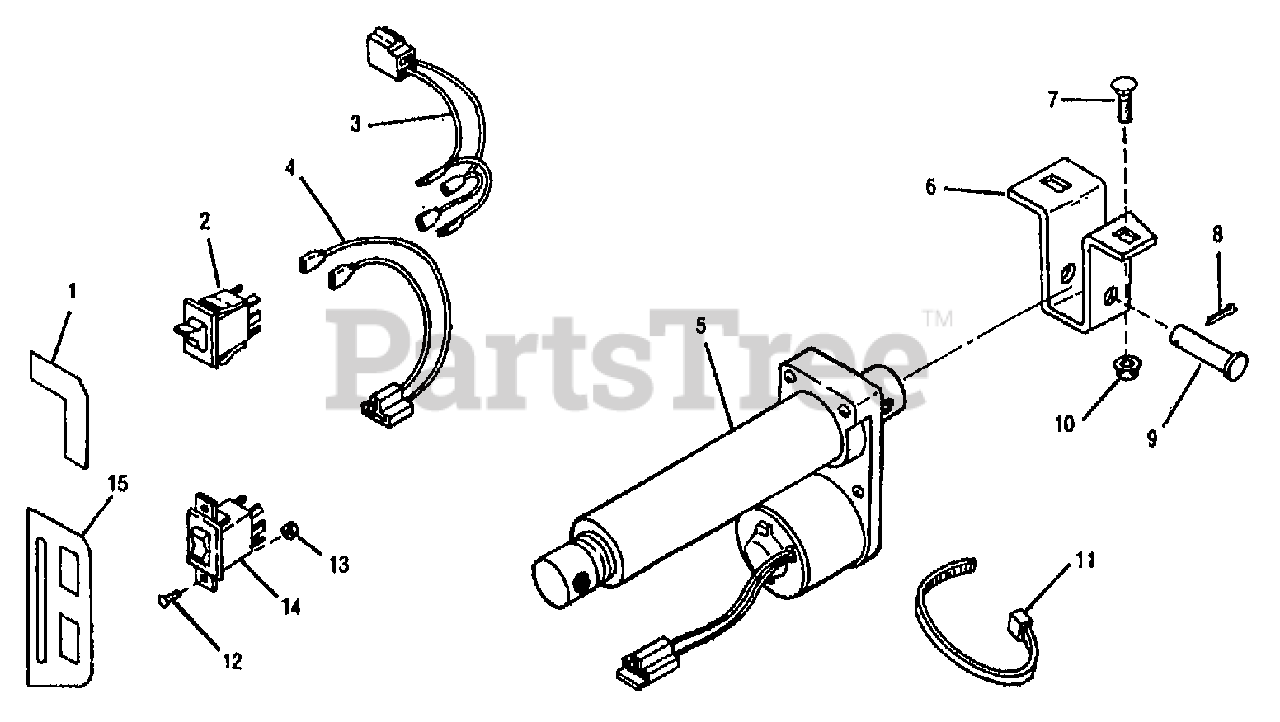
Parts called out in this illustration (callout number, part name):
1	DECAL-LIFT
2	SWITCH
3	HARNESS-ELEC LIFT
4	HARNESS-ACTUATOR
5	SEE MODEL 30900
5	ACTUATOR
6	BRACKET-LIFT
7	SCR-CARR 5/16-18X.75 G2 ZP
8	PIN-COTTER .120X1.00 ZP
9	PIN-CLEVIS .5X2.0 ZP
10	NUT-HFLK 5/16-18 ZP
11	TIE-CABLE NYLON BLACK
12	SCR-FHP #6-32X.50 ZP
13	NUT 6-32 UNC-2B THDS
14	SWITCH-ELEC LIFT
15	DECAL
15	LIFT DECAL
15	SWITCH-LIGHT
